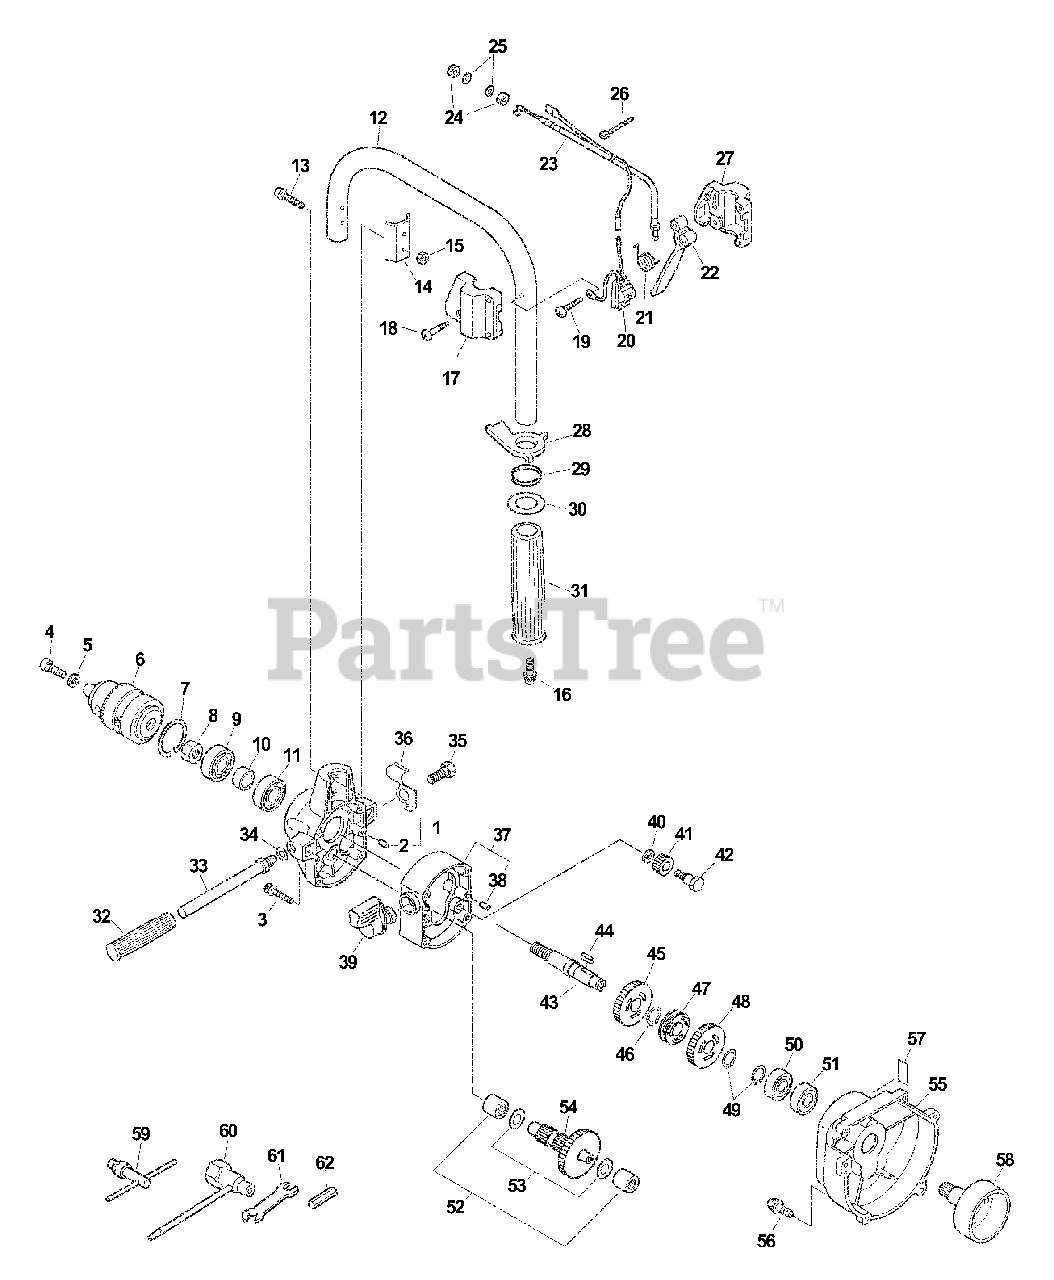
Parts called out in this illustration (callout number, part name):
1	GEAR CASE ASSY
2	PIN - LOCATING
3	SCREW - 5X50
4	SCREW - 6X20
5	WASHER - 6
7	RING, RETAINING - 32
8	NUT - 12
9	BEARING, BALL - 6002
11	BEARING, BALL - 6002
12	HANDLE - REAR
13	SCREW - 5X35
14	PLATE, HANDLE
15	LOCKNUT - 5
16	SCREW - 5X16
17	BRACKET, THROTTLE CONTROL - LEFT
18	SCREW - 4X25
19	SCREW - 4X30
20	IGNITION SWITCH ASSY
21	SPRING, TRIGGER
22	TRIGGER, THROTTLE
23	CONTROL CABLE ASSY
25	WASHER - 6
26	TIE, CABLE
27	BRACKET, THROTTLE CONTROL - RIGHT
28	LEVER, TRIGGER LOCKOUT
29	SPRING, LOCKOUT LEVER
31	GRIP, HANDLE - RIGHT
32	GRIP, HANDLE
33	HANDLE - FRONT
34	WASHER - 10
35	BOLT - 10X15
36	SPRING, FLAT
37	CASE, GEAR
38	PIN - LOCATING
39	LEVER, CLUTCH
40	WASHER - 6
41	GEAR - SPUR
42	BOLT, CLUTCH
43	SHAFT, AXLE
44	KEY - 4X16
45	GEAR - SPUR
46	RING, RETAINING - 15
47	NAIL, CLUTCH
48	GEAR - SPUR
49	RING, RETAINING - 12
50	BEARING, BALL - 6001
51	BEARING, BALL - 6001
52	BEARING, NEEDLE
54	GEAR - SHAFT
55	CASE, FAN
56	SCREW - 4X16
57	LABEL - HOT SURFACE
58	DRUM, CLUTCH
59	KEY, CHUCK
60	T-WRENCH - 10X19mm
61	SPANNER - 17X19mm
